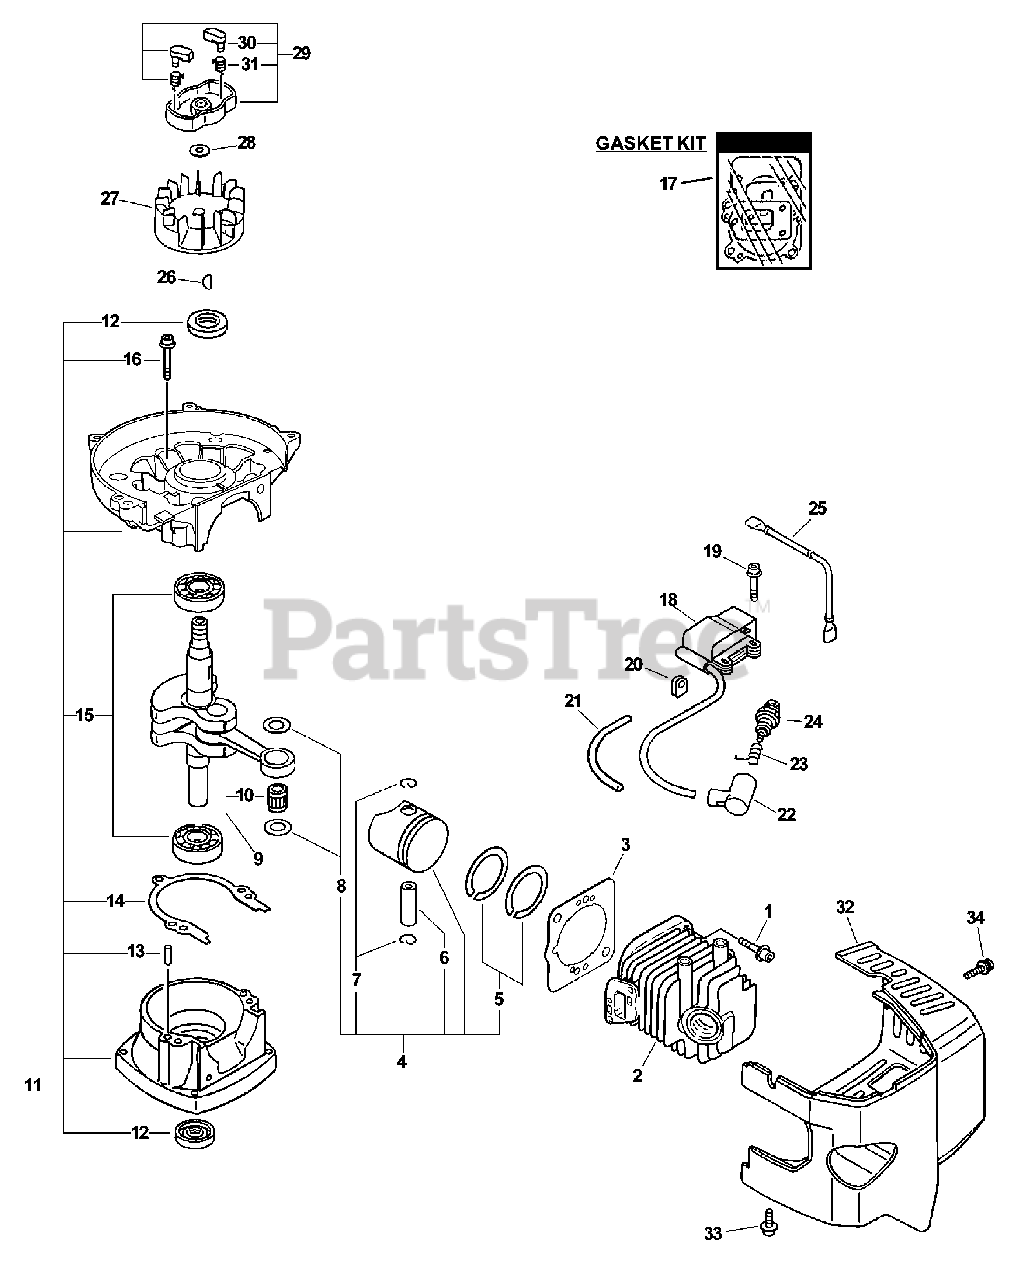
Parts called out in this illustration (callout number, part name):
1	BOLT 5×22
2	CYLINDER
3	GASKET, CYLINDER
4	PISTON KIT
5	RING, PISTON
6	PIN, PISTON 8
7	RING, SNAP
8	WASHER, THRUST
9	CRANKSHAFT ASSY
10	BEARING, NEEDLE 8
11	CRANKCASE KIT
12	SEAL, OIL 12
13	PIN, LOCATING 4
14	GASKET, CRANKCASE
15	BEARING, BALL - 6201 C3
16	BOLT 5×28
17	GASKET KIT
18	COIL, IGNITION
19	BOLT 4×20
21	TUBE, INSULATOR
22	CAP, SPARK PLUG
23	TERMINAL, SPARK PLUG
24	SPARK PLUG - BPMR7A
25	LEAD - IGNITION
27	FLYWHEEL
28	WASHER, SPRING 8
29	PAWL ASSY, STARTER
30	PAWL, STARTER - BLACK
31	SPRING, RETURN
32	COVER, ENGINE
33	SCREW 4×18
34	BOLT 4×8
